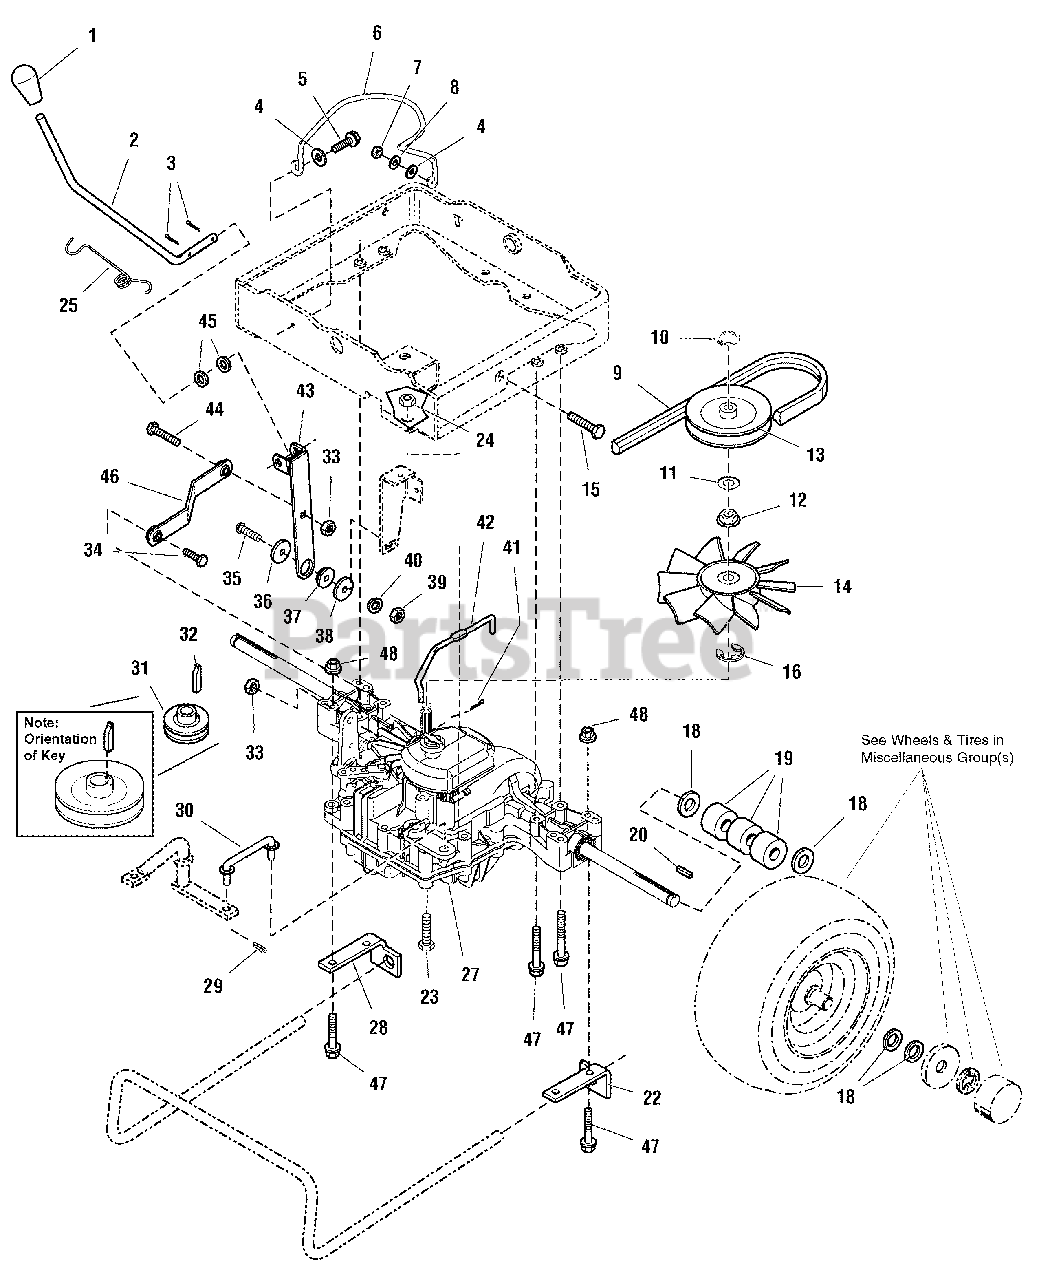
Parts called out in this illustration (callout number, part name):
3	PIN, Cotter
5	SCREW, Hex Washer Head Taptite, 5/16-18 x 3/4
7	NUT, Hex 5/16-18
8	LOCKWASHER, 5/16
12	SPLINE COLLAR
14	FAN
15	CAPSCREW, 5/16-18 x 1
16	"E" RING
20	KEY
22	ANCHOR, Torsion Bar LH
23	CAPSCREW, Hex Head Flange Whizlock, 5/16-18 x 1-3/4
24	NUT, Hex Flange Whizlock, 5/16-18
27	TRANSMISSION ASSEMBLY
28	ANCHOR, Torsion Bar RH
29	PIN, Cotter
31	PULLEY & HUB ASSEMBLY
32	KEY, Hi-Pro
33	NUT, Hex Flange Lock, 5/16-18
34	CAPSCREW, 5/16-18 x 1-1/4
35	CARRIAGE BOLT, 3/8-16 x 1-1/4
36	WASHER
39	NUT, Hex, 3/8-16
40	LOCKWASHER, 3/8
41	PIN, Cotter
43	LEVER & CLEVIS ASSEMBLY
44	CARRIAGE BOLT, 5/16-18 x 1
46	LINK, Transmission
47	SCREW, Hex Washer Head Taptite, 5/16-18 x 2-1/2
48	NUT, Hex Flange Whiz Lock 5/16-18 LG
